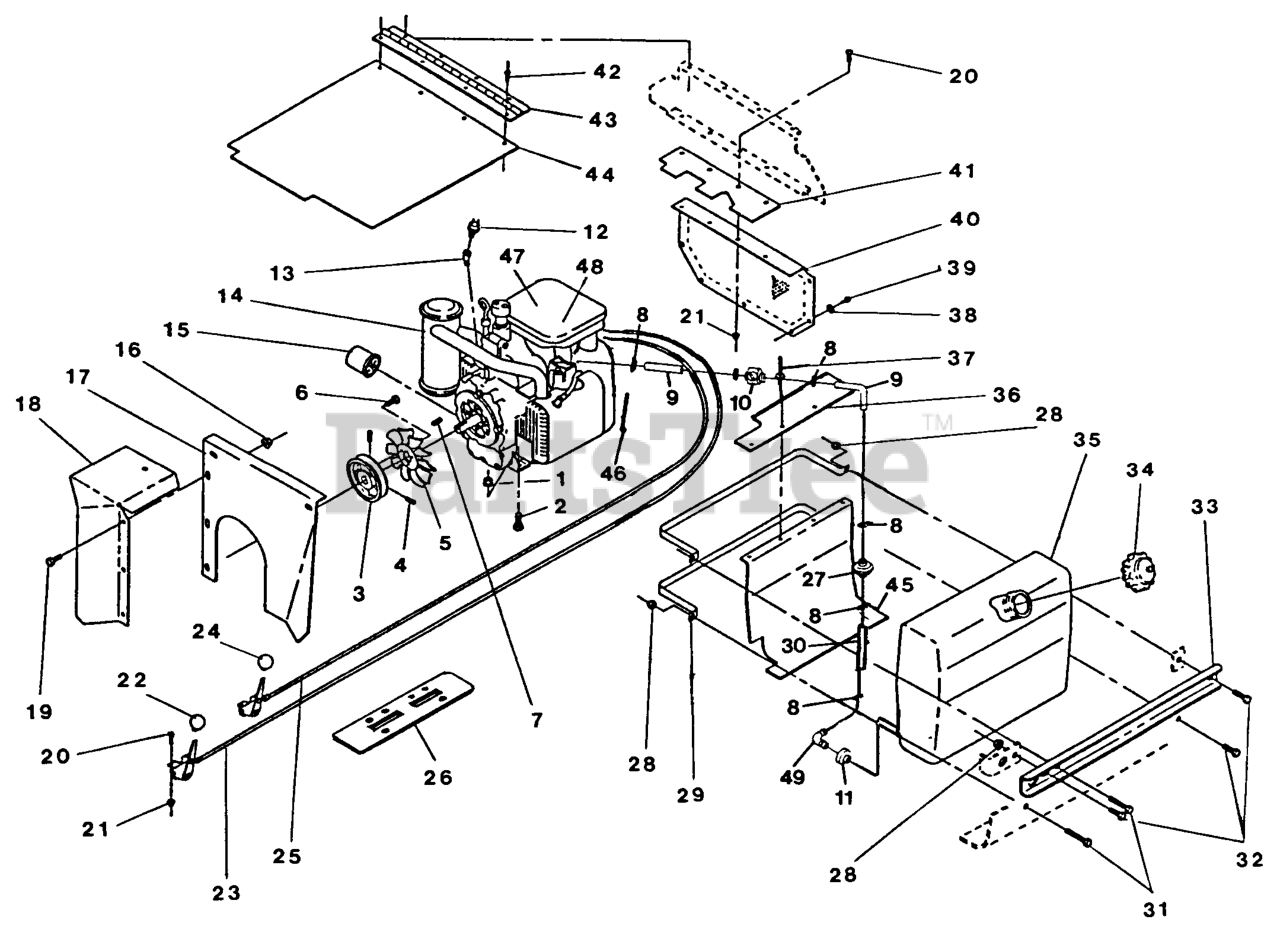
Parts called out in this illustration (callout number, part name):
4	SCREW-SET
9	FUEL LINE
10	VALVE-FUEL
17	SHIELD,HEAT FRONT
22	KNOB-BALL
24	KNOB-BALL, BLACK
29	STRAP,FUEL TANK 3.8GAL
30	HOSE-FUEL
31	Bolt, Tap 1/4-20 X 2-1/2
34	CAP-FUEL
36	BAFFLE,ENGINE LH
37	RIVET-POP
42	Pop Rivet, Steel 3/16 X .250
43	HINGE,ENGINE COVER
46	TIE-CABLE
49	ELBOW-TANK, FUEL
